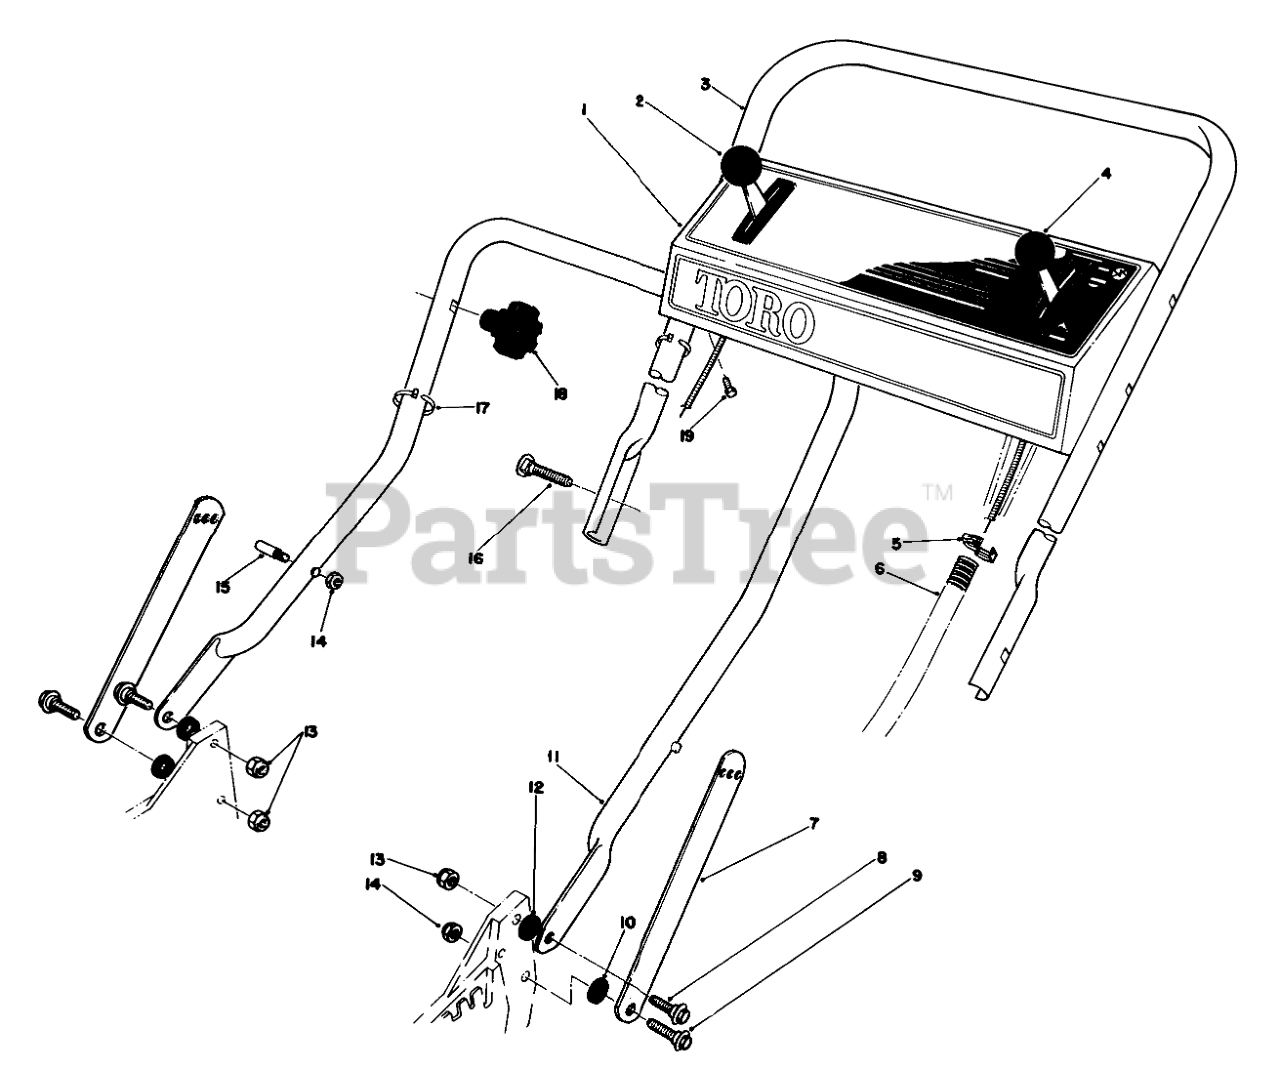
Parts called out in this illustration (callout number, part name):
1	Panel-Control
2	GROUND SPEED CONTROL
3	UPPER HANDLE
4	SERVICE THROTTLE CONTRO
5	FITTING-RING
6	CONTROL CABLE COVER
7	Handle Latch
8	SCREW-SHOULDER
9	SCREW-SHOULDER
10	SPACER
11	LOWER HANDLE ASM
12	SPACER
13	NUT-LOCK, NI
14	NUT-LOCK, NI
15	HANDLE PIN
16	5/16-18 X 2 HNDLE SCREW
17	TIE-CABLE
19	SCREW-HWHTF
